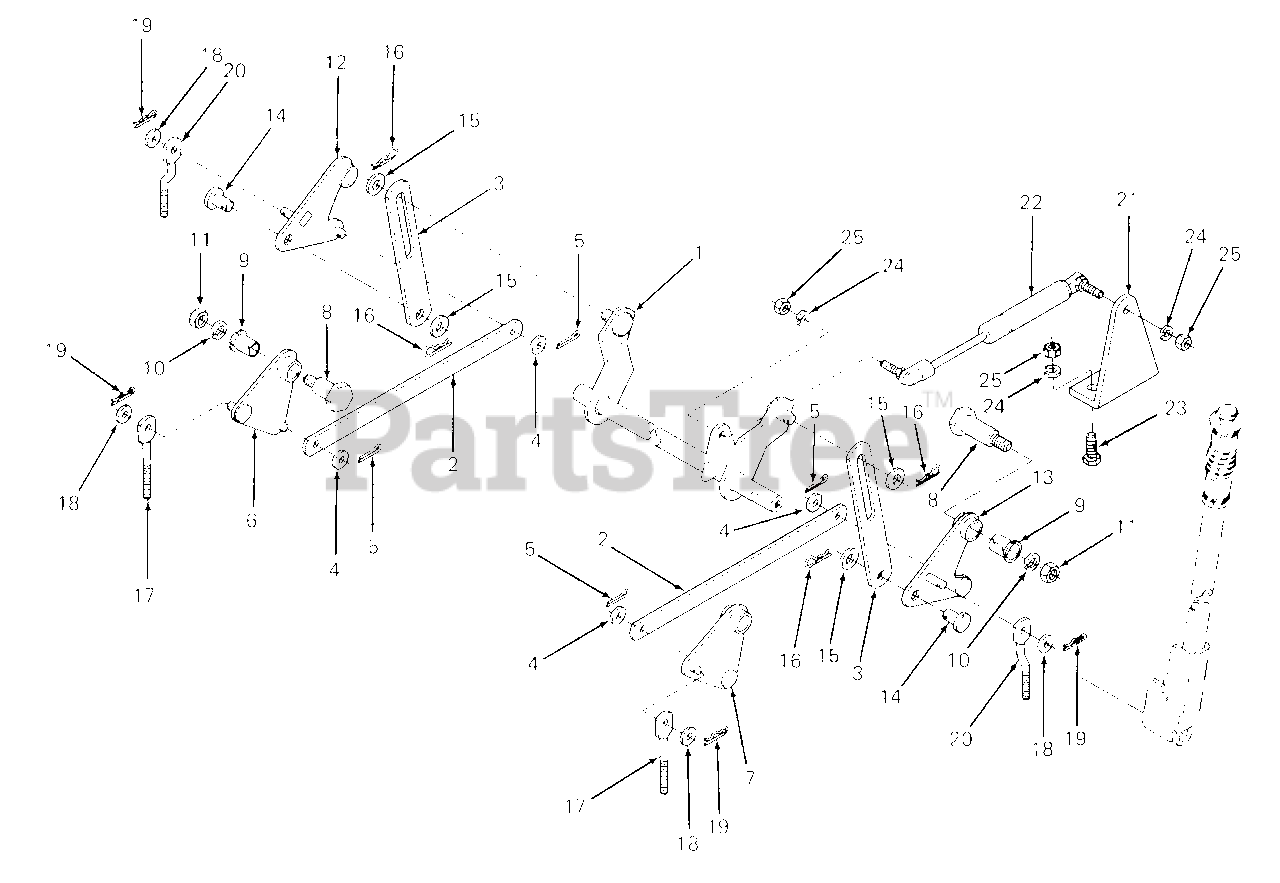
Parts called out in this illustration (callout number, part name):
1	Shaft Assy, Lift
3	Link, Lift
4	Washer, Flat, .406 X 1.0 X .030 Thk
5	Pin, Cotter, 1/8 X 3/4 Lg
6	Cam Assy, Rear Lift - LH
7	Cam Assy, Rear Lift - RH
8	Screw, Shoulder, .625 X .960
9	Bearing, Flanged Nyliner
10	Washer, Lock, 3/8
11	Nut, Hex Center Lock, 3/8-16 GR5
12	Cam Assy, Front Lift - LH
14	Pin, Clevis, .50 Dia X .62 Lg
15	Washer, Flat, .510 X 1.0 X .06 Thk
16	Pin, Internal Cotter
17	Link, Rear Lift
18	Washer, Flat, .406 X .75 X .063 Thk
19	Pin, Internal Cotter
20	Link, Front Lift
21	Bracket, Spring
22	Spring Assy, Gas
23	Bolt, 5/16-18 X 7/8 Lg GR5
24	Washer, Lock, 5/16
25	Nut, Hex, 5/16-18 GR5
